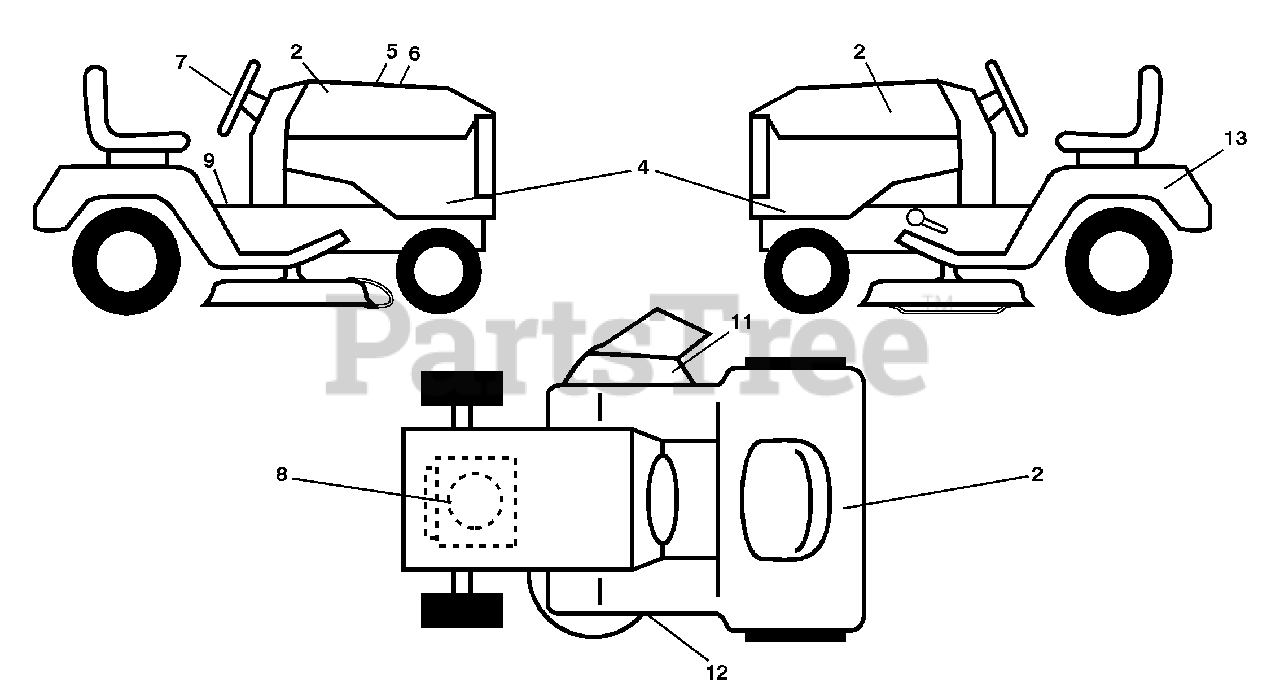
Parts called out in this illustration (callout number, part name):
2	Decal, Hood
4	Decal, Hood Panel
5	Decal, Customer Respons.
6	Decal, Replacement
7	Decal, Steering Wheel
8	Decal, Engine
9	Decal, Battery Dnge/Poi
11	Decal, Warning
12	Decal, Mower V-Belt Schematic
13	Decal, Fender Warn./Instructions
13	Decal, Bypass
13	Pad, Footrest, LH
13	Pad, Footrest, RH
13	Manual, Owner's
